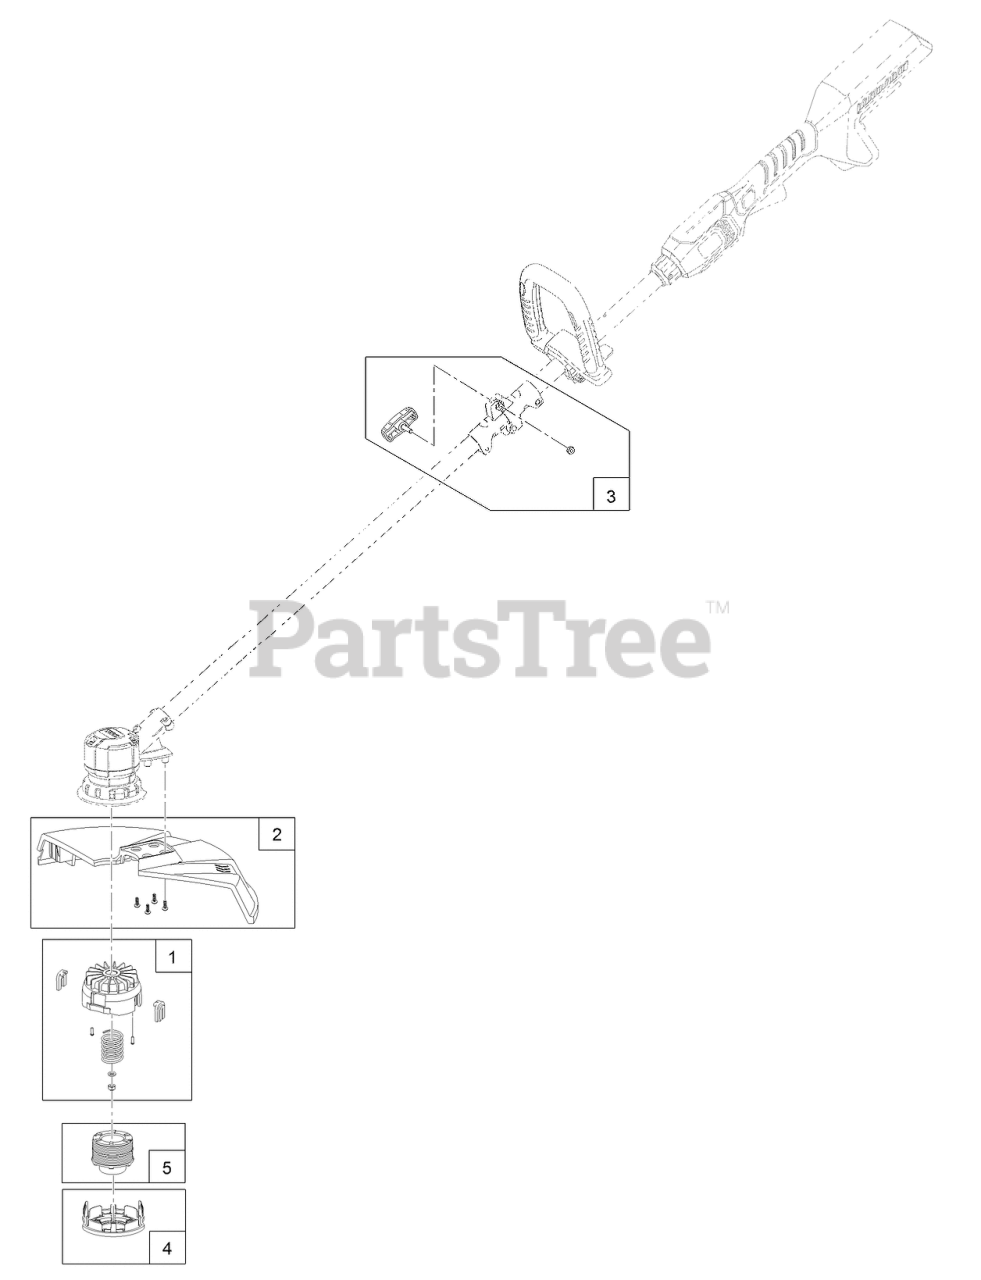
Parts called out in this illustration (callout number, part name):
1	HEAD-FEED, BUMP
2	SHIELD-GRASS
3	SHAFT CONNECTION HARDWARE KIT
4	RETAINER-CAP, SPOOL
5	3-PACK DUAL-LINE TRIMMER SPOOL
